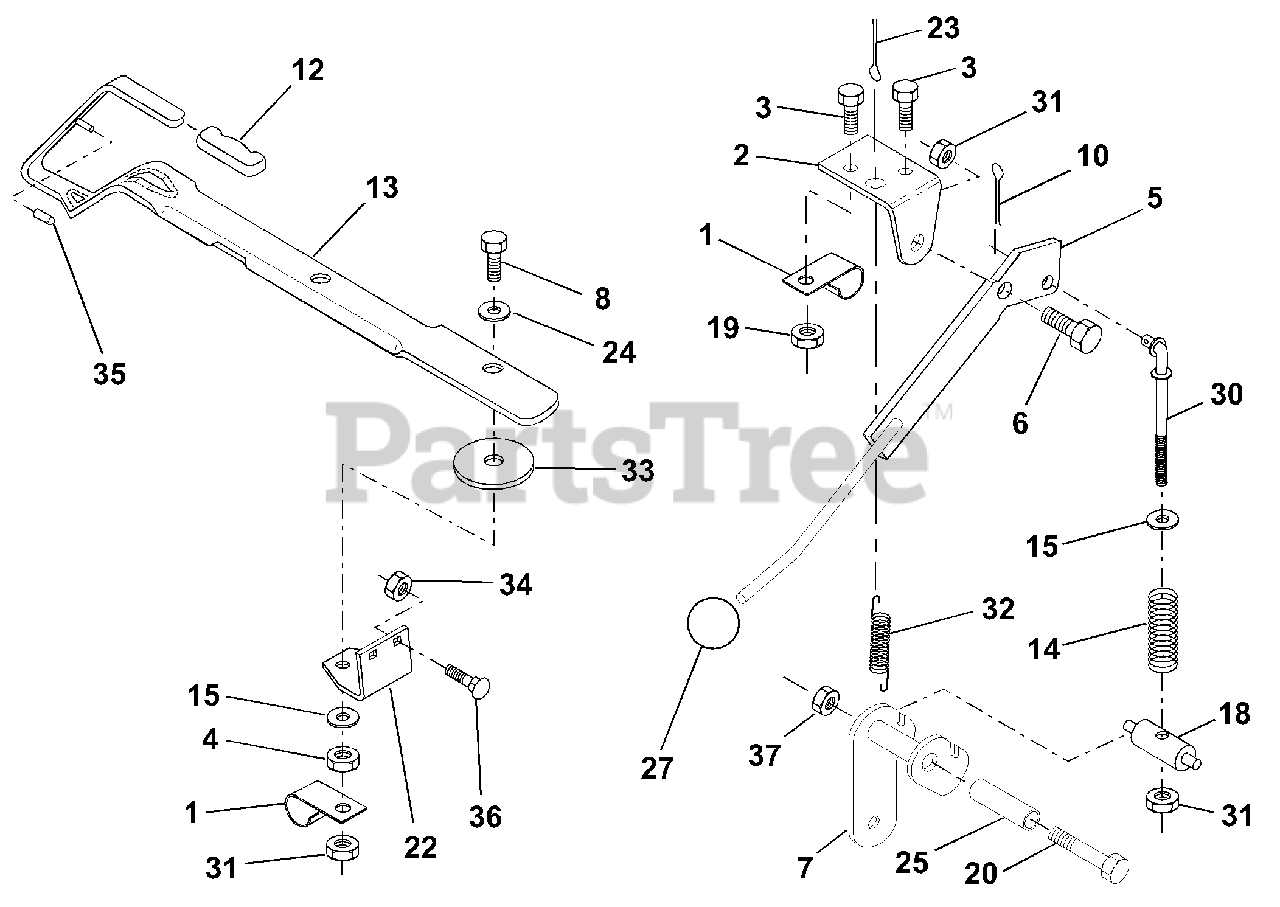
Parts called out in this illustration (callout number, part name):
1	Clip, Insulated
2	Bracket, Mower Clutch
3	Bolt, Hex Hd, Fin. 1/4-20 UNC x 1/2 Grade 5
4	Nut, Centerlock 3/8-16 UNC
5	Assembly, Clutch Lever
6	Bolt, Shoulder
7	Assembly, Mower Clutch Arm
8	Bolt, Hex Head 3/8-16 UNC x 1-1/2
10	Pin, Cotter 1/8 x 3/4
12	Handle, Lift Lever
13	Assembly, Lift Handle
14	Spring, Compression
15	Washer 13/32 x 1 x 11 Gauge
18	Trunnion, Threaded 3/8-16
19	Nut, Crownlock 1/4-20
20	Bolt, Hex Hd, Fin. 3/8-16 UNC x 2-3/4
22	Bracket, Lift Lever
23	Pin, Cotter 3/32 x 3/4
24	Washer 25/64 x 1-1/4 x 12 Gauge
25	Tube, Spacer
30	Rod, Tension, Clutch
31	Nut Lock Hex w/wsh 3/8 - 16
32	Spring, Extension, Return
33	Washer .390 x 1.437 x .074
34	Nut, Lock Hx w/Ins 5/16-18
35	Cap, Vinyl, Red
36	Bolt, Carriage 5/16-18 x 3/4
37	Nut Crownlock 3/8-16
